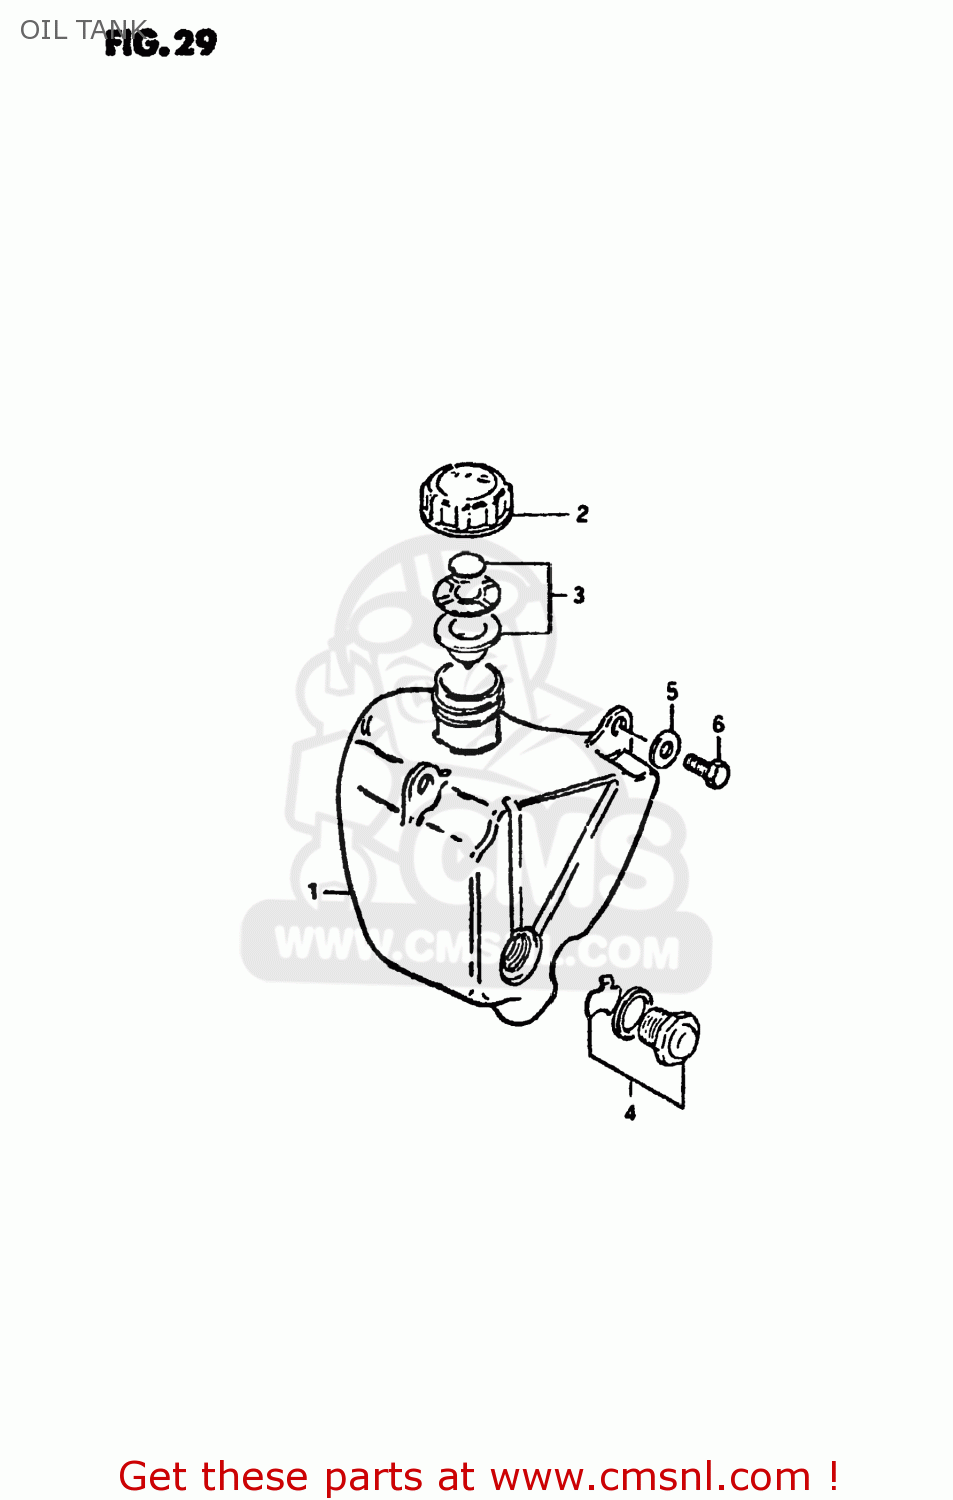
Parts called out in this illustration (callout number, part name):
1	TANK,OIL
2	CAP,OIL TANK
3	GASKET SET (NAS)
4	LENS SET,OIL LEVEL
5	WASHER
6	BOLT, UPPER
